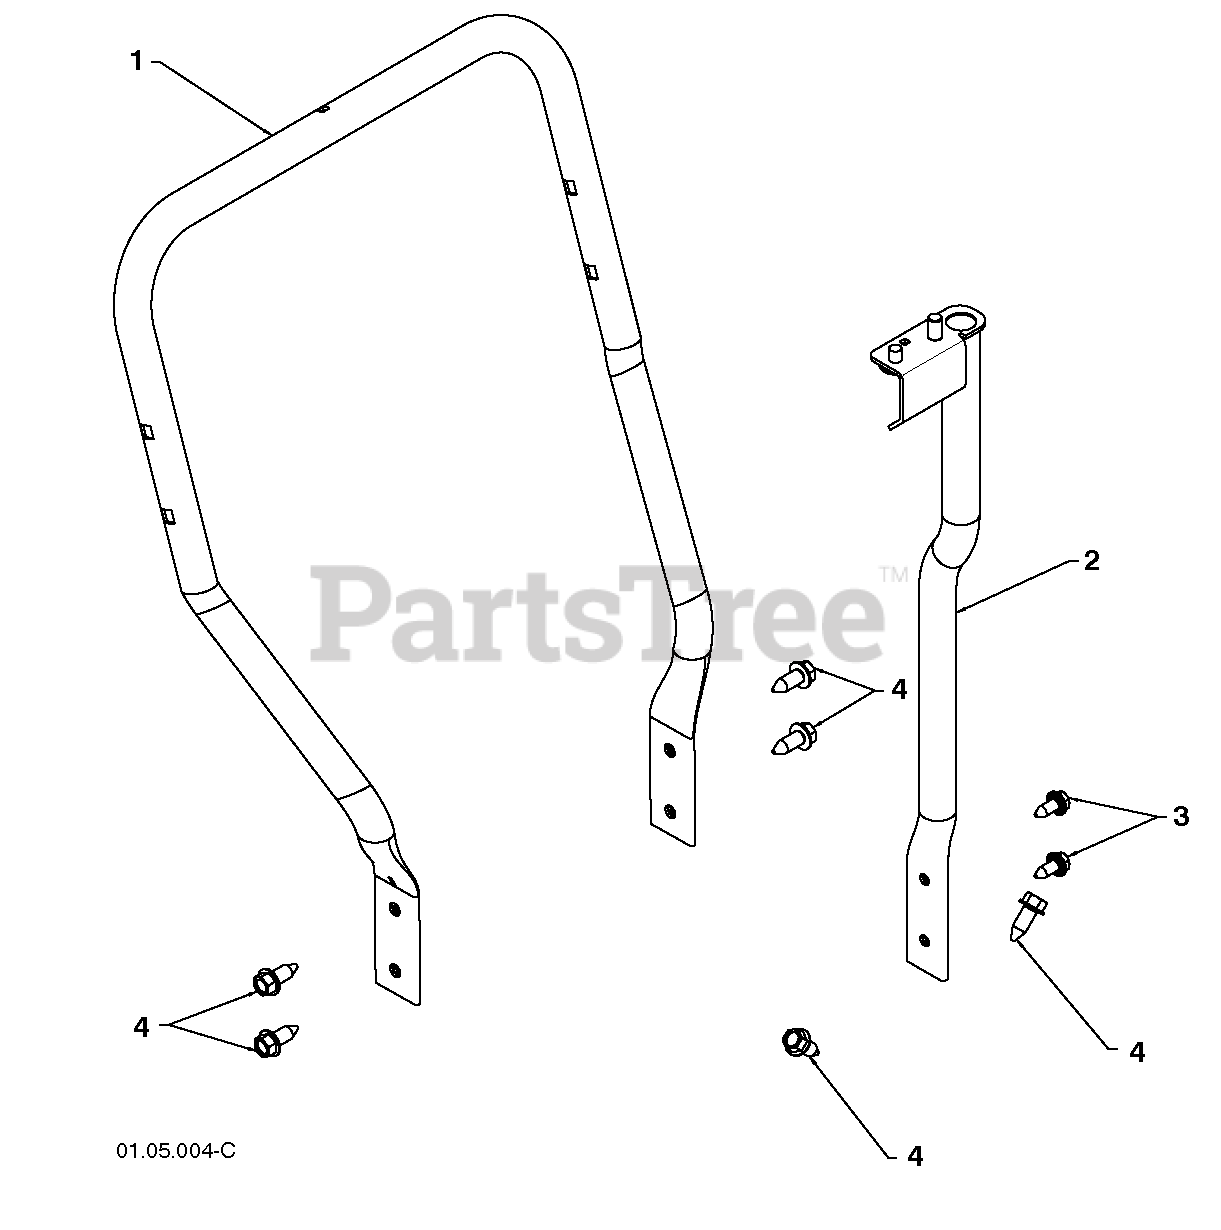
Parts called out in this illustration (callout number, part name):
1	LOWER TUBE
3	BOLT 5/16-18 X .750
4	SCREW 3/8-16 X 1.00
